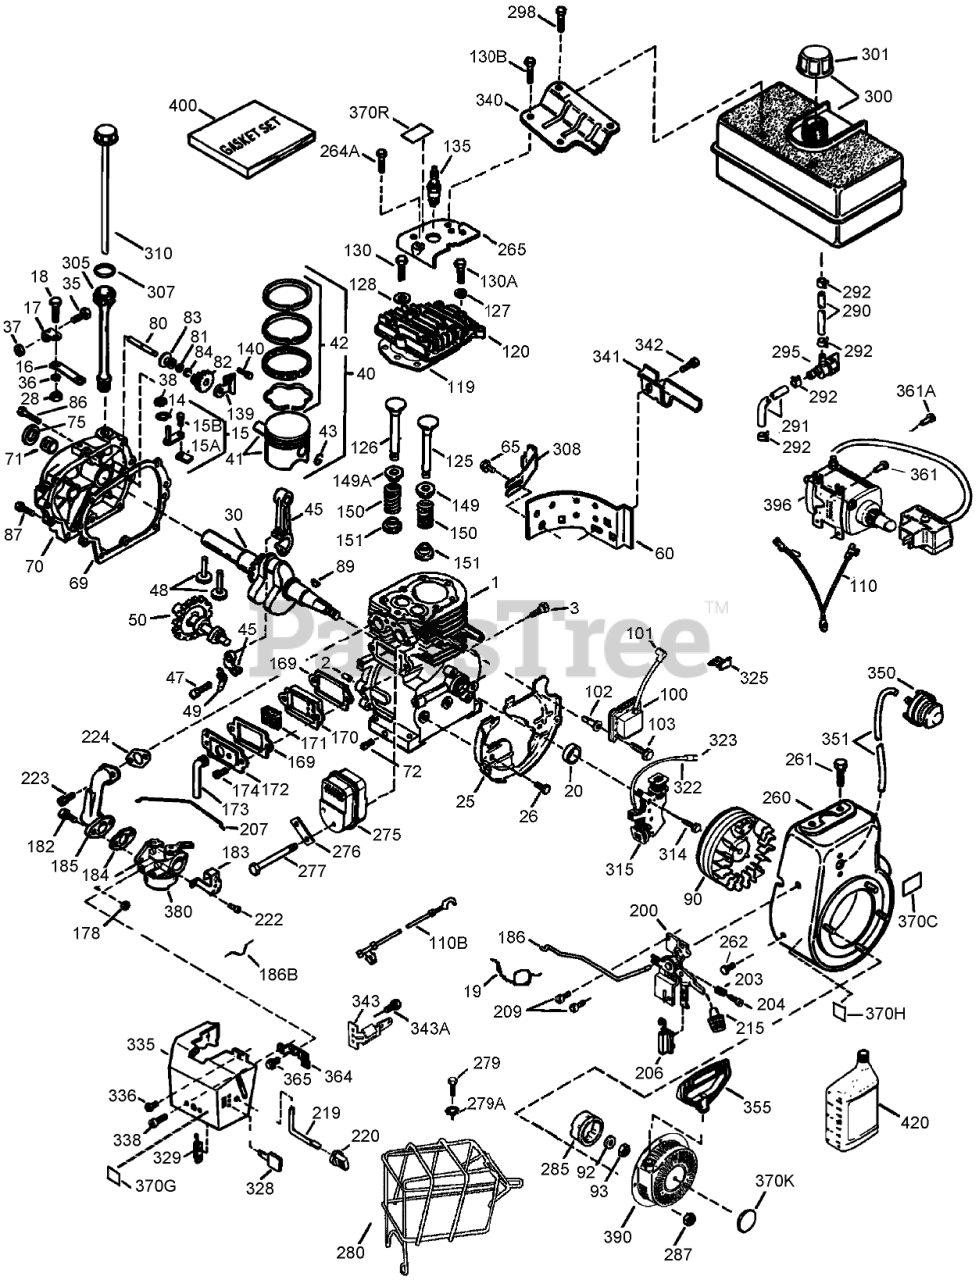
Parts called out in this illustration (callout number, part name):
1	Cylinder ASM (Includes 2, 20, 72)
2	Pin-Dowel
3	Screw (1/4-20x1/2)
14	Washer-Flat
15	Rod-Governor (Includes 15A, 15B)
15A	Yoke-Governor
15B	Screw (6-40x5/16)
16	Lever-Governor
17	Clamp-Lever, Governor
18	Screw (T-15, 8-32x7/16)
19	Spring-Throttle
20	Seal-Oil
25	Baffle-Housing, Blower
26	Screw (1/4-20x19/32)
28	Nut-Lock
30	Crankshaft
35	Screw
36	Washer-Lock
37	Nut-Lock
38	Ring-Retaining
40	Piston Pin and Ring ASM (STD)
40	Piston Pin and Ring ASM (.010)
40	Piston Pin and Ring ASM (.020)
41	Piston and Pin ASM (STD) (Includes 43)
41	Piston and Pin ASM (.010) (Includes 43)
41	Piston and Pin ASM (.020in OS) (Includes 43)
42	Ring Set (STD)
42	Ring Set (.010)
42	Ring Set (.020)
43	Retaining Ring-Piston Pin
45	Connecting Rod ASM (Includes 47, 49)
47	Bolt-Rod, Connecting
48	Lifter-Valve
49	Dipper-Oil
50	Camshaft (MCR)
60	Extension-Housing, Blower
65	Screw
69	Gasket-Cover, Cylinder
70	Cover-Cylinder (Includes 71, 75, 80-84)
71	Bushing-Crankshaft
72	Plug-Drain, Oil (SQH 1/4-18)
75	Seal-Oil
80	Shaft-Governor
81	Washer
82	Governor Gear ASM (Includes 81)
83	Spool-Governor
84	Ring-Retaining
86	Screw (1/4-20x1-3/16)
87	Screw (1/4-20x1-11/16)
89	Key-Flywheel
90	Flywheel ASM
92	Washer-Belleville
93	Nut-Flywheel
100	Ignition-State, Solid (Includes 101)
101	Cover-Spark Plug
102	Stud-Mounting, Solid State
103	Screw (T-15, 10-24 x 15/16)
110	Wire-Ground
110B	Wire-Ground
119	Gasket-Head, Cylinder
120	Head-Cylinder
125	Valve-Exhaust (STD) (Includes 151)
125	Valve-Exhaust (1/32in OS) (Includes 151)
126	Valve-Intake (STD) (Includes 151)
127	Washer-Flat
128	Washer-Belleville
130	Screw (5/16-18x1-1/2)
130A	Screw (5/16-18x1-25/32)
130B	Screw (5/16-18x39/64)
135	Spark Plug-Resistor (R J19 L M)
139	Bracket-Gear, Governor
140	Screw (10-24x1/2)
149	Cap-Spring, Valve
149A	Cap-Spring, Valve
150	Spring-Valve
151	Keeper-Spring, Valve
169	Gasket-Cover, Valve
170	Body-Breather
171	Element-Breather
172	Cover-Valve
173	Tube-Breather
174	Screw
178	Nut and Lock Washer (1/4-28)
182	Screw (1/4-28x1)
183	Bracket-Choke
184	Gasket-Carburetor To Intake Pipe
185	Pipe-Intake
186	Link-Governor
186B	Spring-Choke
200	Bracket-Control (Includes 203, 204)
203	Spring-Compression
204	Screw (T-10, 5-40x7/16)
206	Terminal
207	Link-Throttle
209	Screw (10-32 x 1/2)
215	Knob-Control
219	Rod-Choke
220	Knob-Control
222	Screw (10-32 x 1/2)
